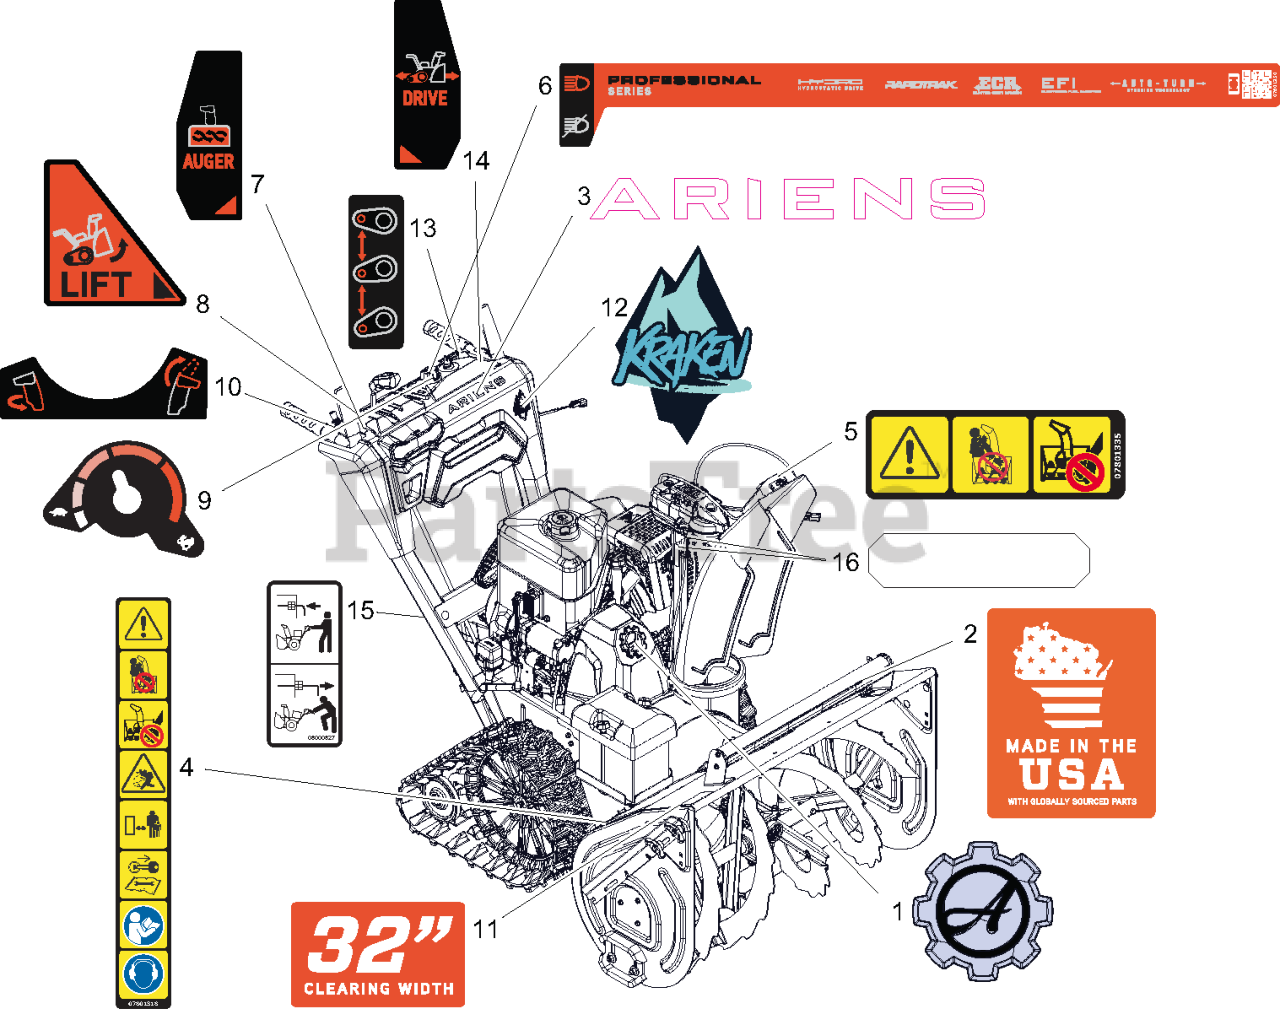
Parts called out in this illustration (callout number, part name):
1	DECAL, ARIENS - GEAR BADGE
2	DECAL- MADE IN USA
3	DECAL- ARIENS - 7.46"
4	DECAL- SAFETY - DANGER
5	DECAL- DANGER
6	DECAL- DASH - PRO TRK ACTUATOR
7	DECAL- CONTROL - AUGER
8	DECAL- CONTROL - TRACK LIFT
9	DECAL- CONTROL - EFI SPEED
10	DECAL- CONTORL - ECR
11	DECAL- CLEARING - 32
12	DECAL- BADGE - KRAKEN
13	DECAL- CONTROL - ACTUATOR
14	DECAL- CONTROL - DRIVE TRACK
15	DECAL, BYPASS
16	DECAL,REFLECTIVE,GEAR COVER
